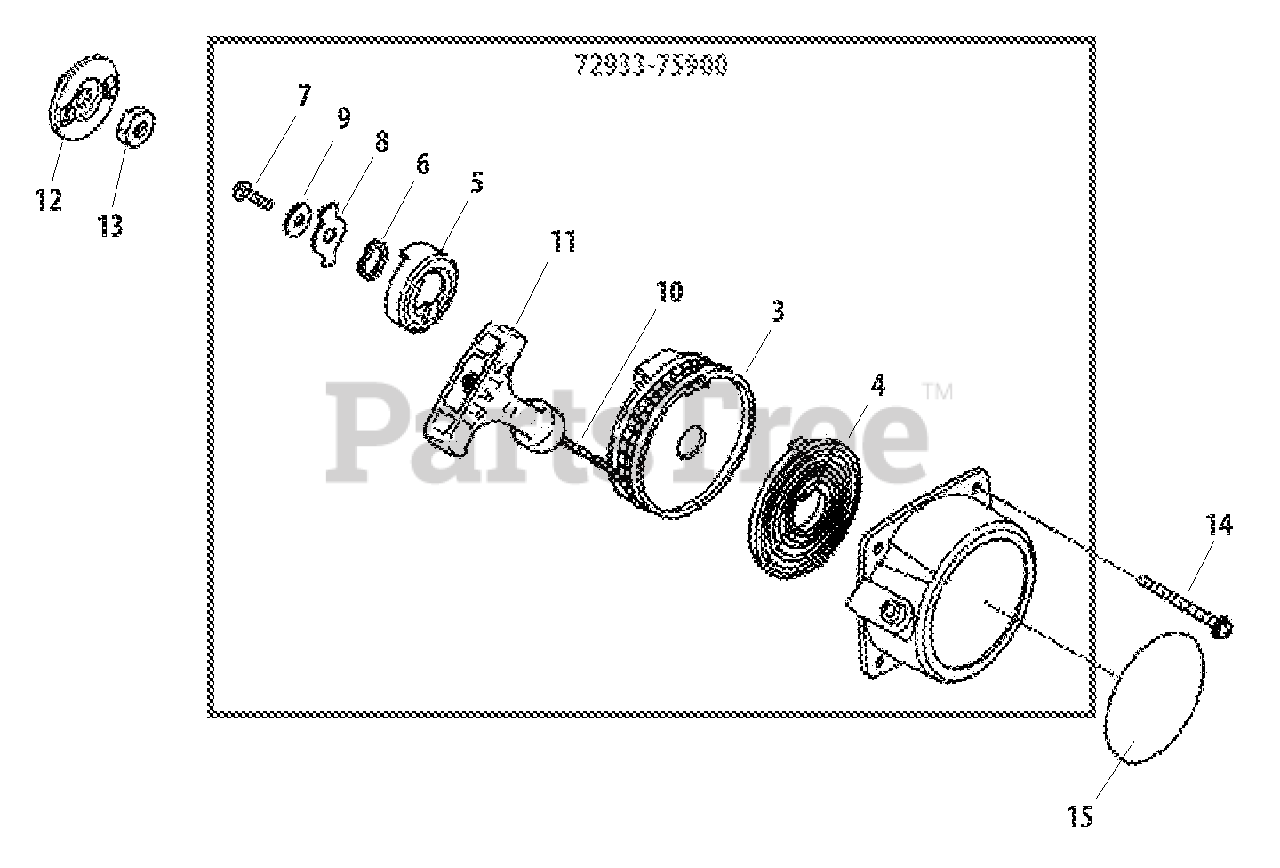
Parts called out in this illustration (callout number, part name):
3	REEL, ROPE
4	SPRING, REWIND
5	PAWL, STARTER
6	WASHER - SPRING
7	SCREW - 5
8	RETAINER
9	WASHER - 5
10	ROPE, STARTER
11	GRIP, STARTER
12	PAWL
13	NUT - 8
14	SCREW - 4X12
15	LABEL - SHINDAIWA PROFESSIONAL
72933-75900	STARTER ASSY
